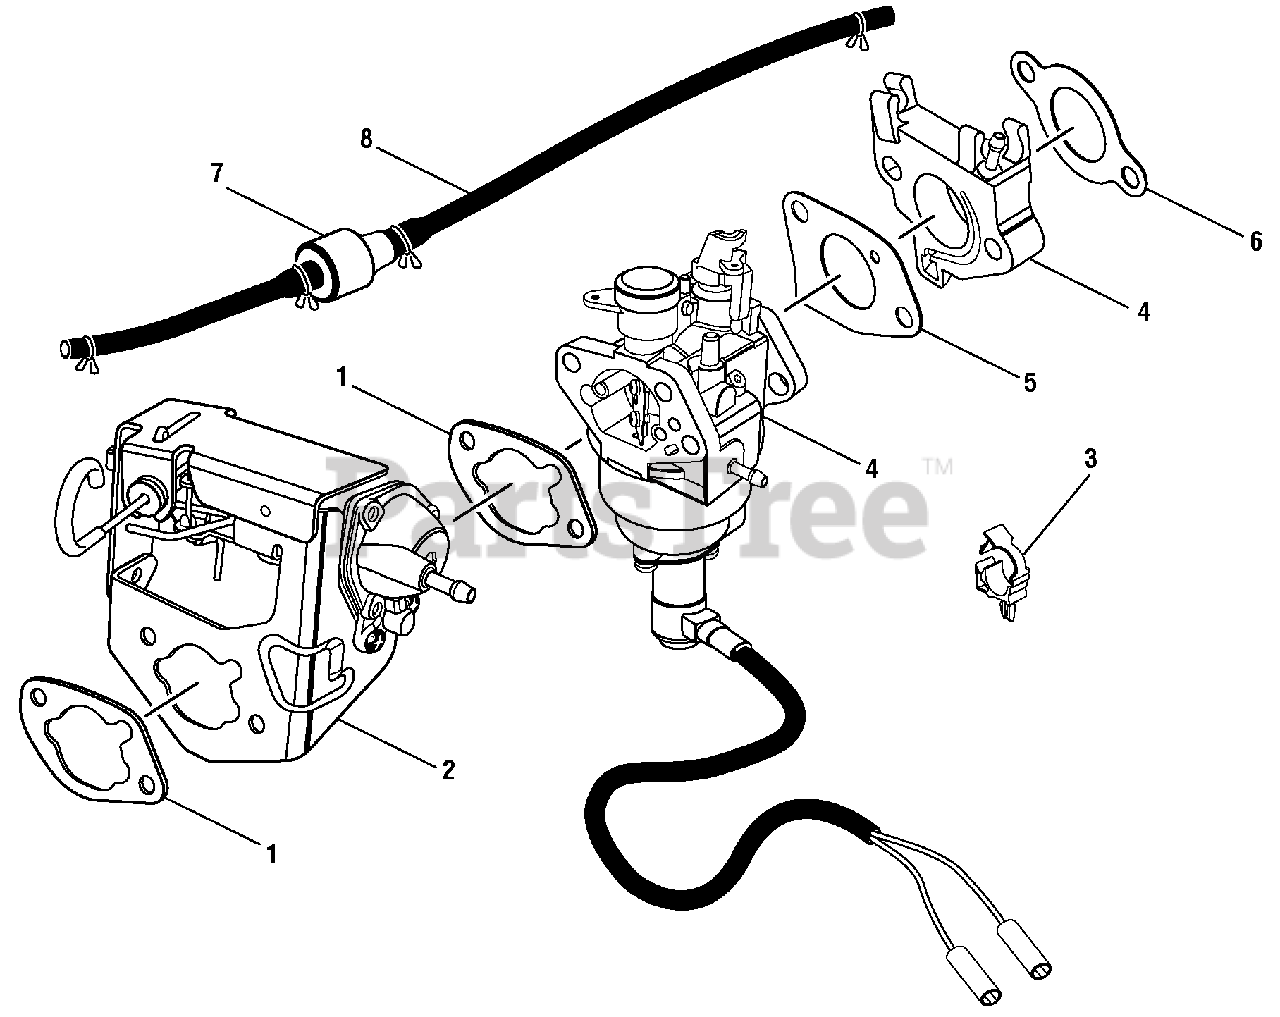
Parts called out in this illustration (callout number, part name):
1	Air Cleaner Gasket
2	Choke Assembly
3	Fuel Line Clamp (Holder)
4	Carburetor Assembly
5	Carburetor Gasket
6	Carburetor Inlet Gasket
7	Check Valve
8	Check Valve Assembly
